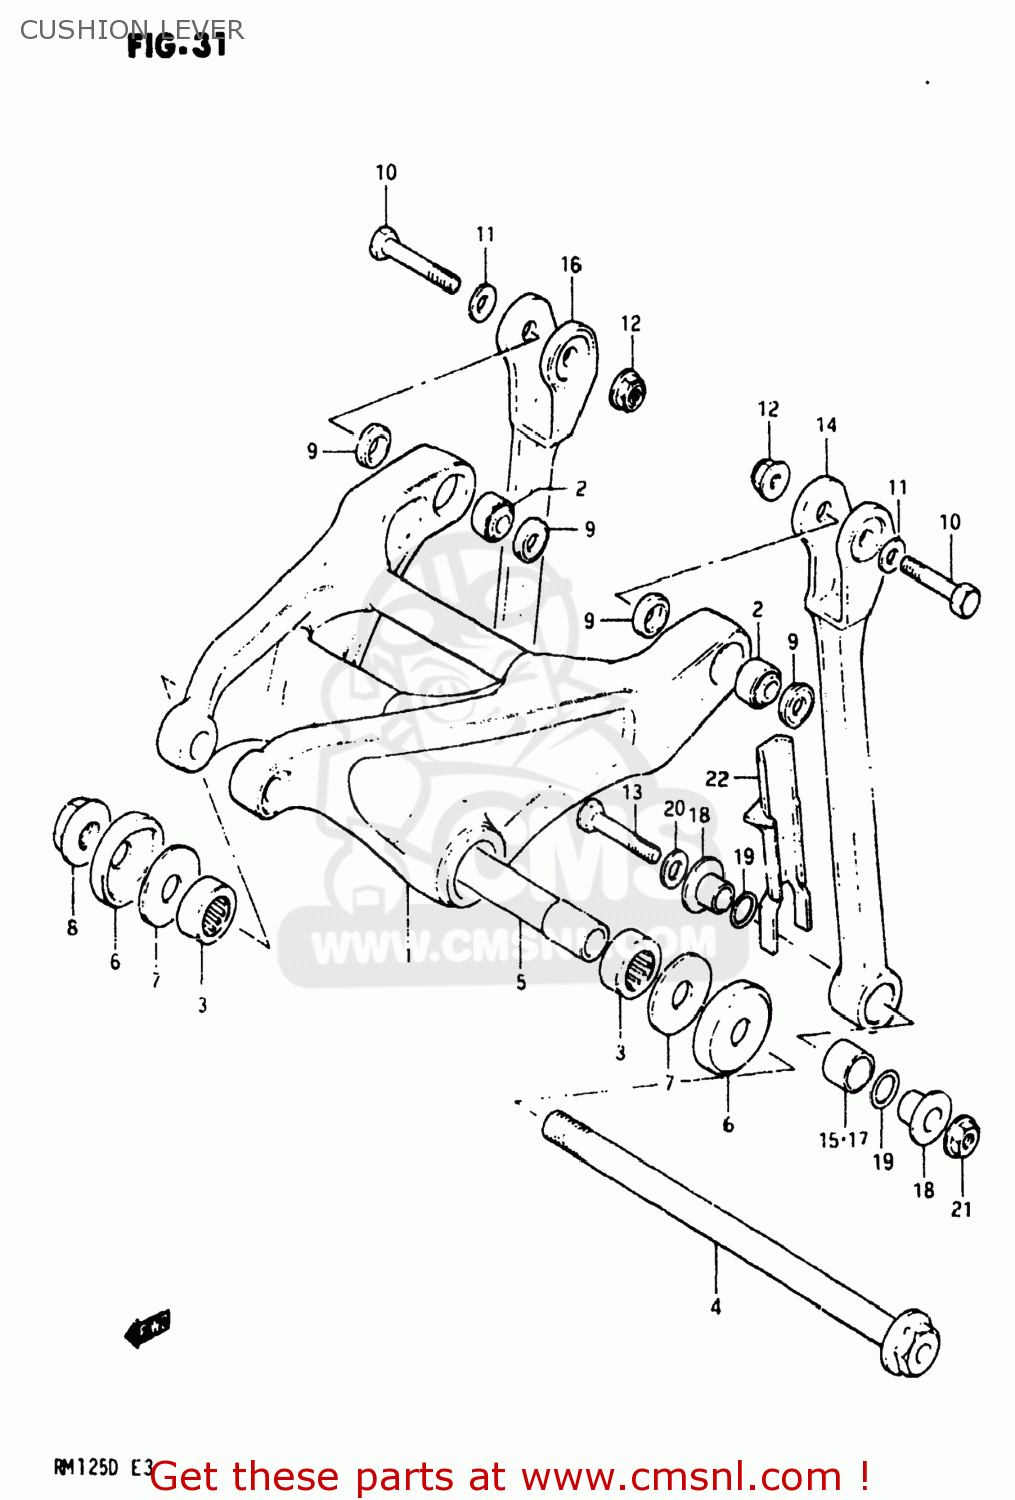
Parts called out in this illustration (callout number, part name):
1	LEVER SET,REAR CUSHION
2	BEARING(8X18X11)
3	BEARING(17X26X20)
4	SHAFT,REAR CUSHION LEVER
5	SPACER,REAR CUSHION LEVER
6	DUST SEAL
7	WASHER(12X35X2)
8	NUT 12MM
9	DUST SEAL,RR CUSHION LOD UPR
10	BOLT,REAR CUSHION LEVER
11	WASHER
12	NUT
13	BOLT,REAR CUSHION LEVER
14	LEVER SET,REAR CUSHION
15	BUSHING
16	LEVER ASSEMBLY,REAR CUSHION
17	BUSHING
18	SPACER,RR CUSHION ROD LWR
19	DUST SEAL,REAR CUSHION
20	WASHER
21	NUT
22	PROTECTOR,REAR CUSHION R
